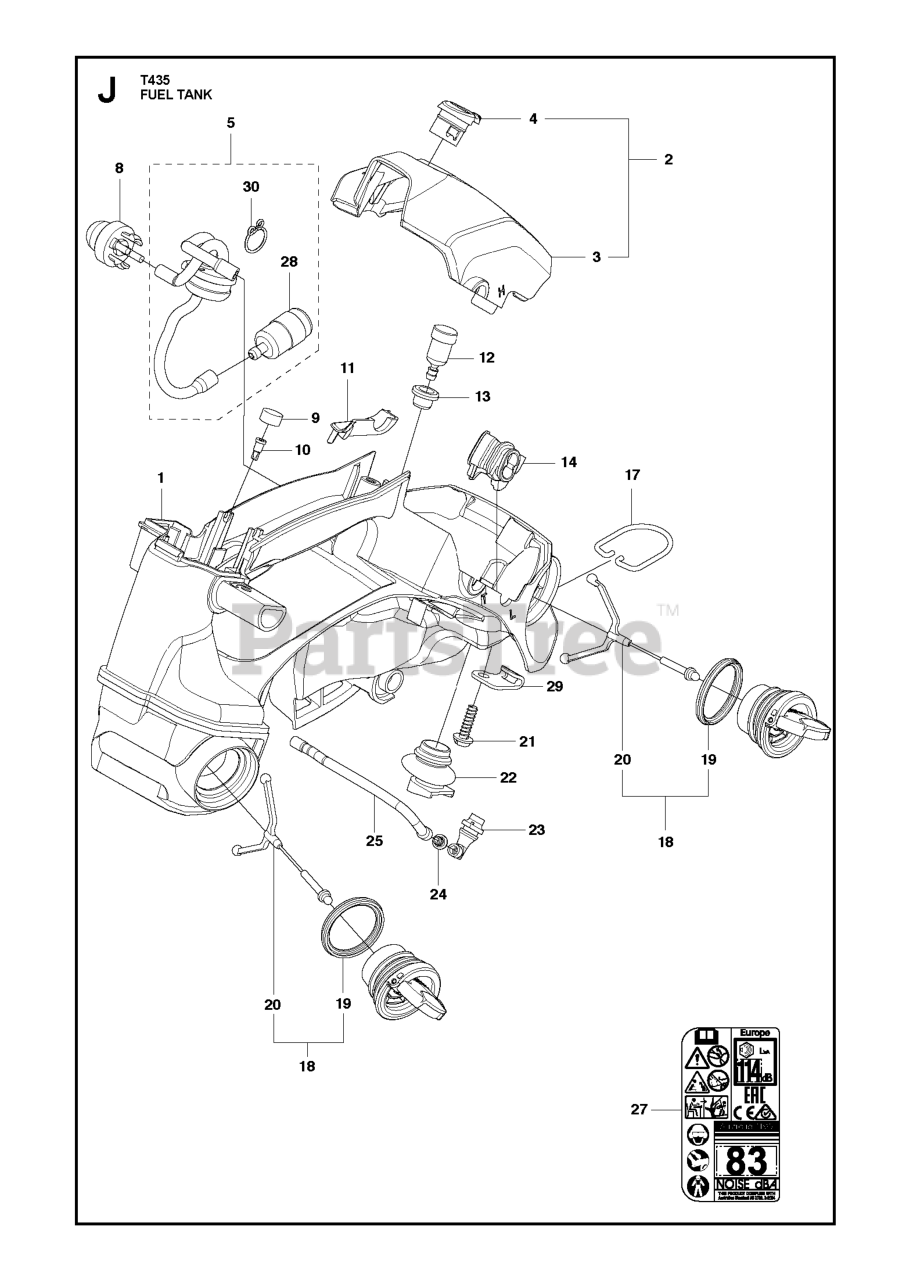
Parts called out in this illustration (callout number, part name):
1	HANDLE COMP ORANGE
2	COVER COMP
3	COVER CLEANER
5	PIPE ASSY
5	PIPE COMP
8	PUMP ASSY
9	BREATHER SEAL
10	AIR CONTROL BREATHER
11	BRACKET KNOB
12	BREATHER
13	GROMMET
14	GUIDE CARB
18	TANK CAP ASSY
19	GASKET TANK CAP
21	SCREW (RPLS 267132210)
23	PIPE
25	PIPE
29	PLATE EYELET
